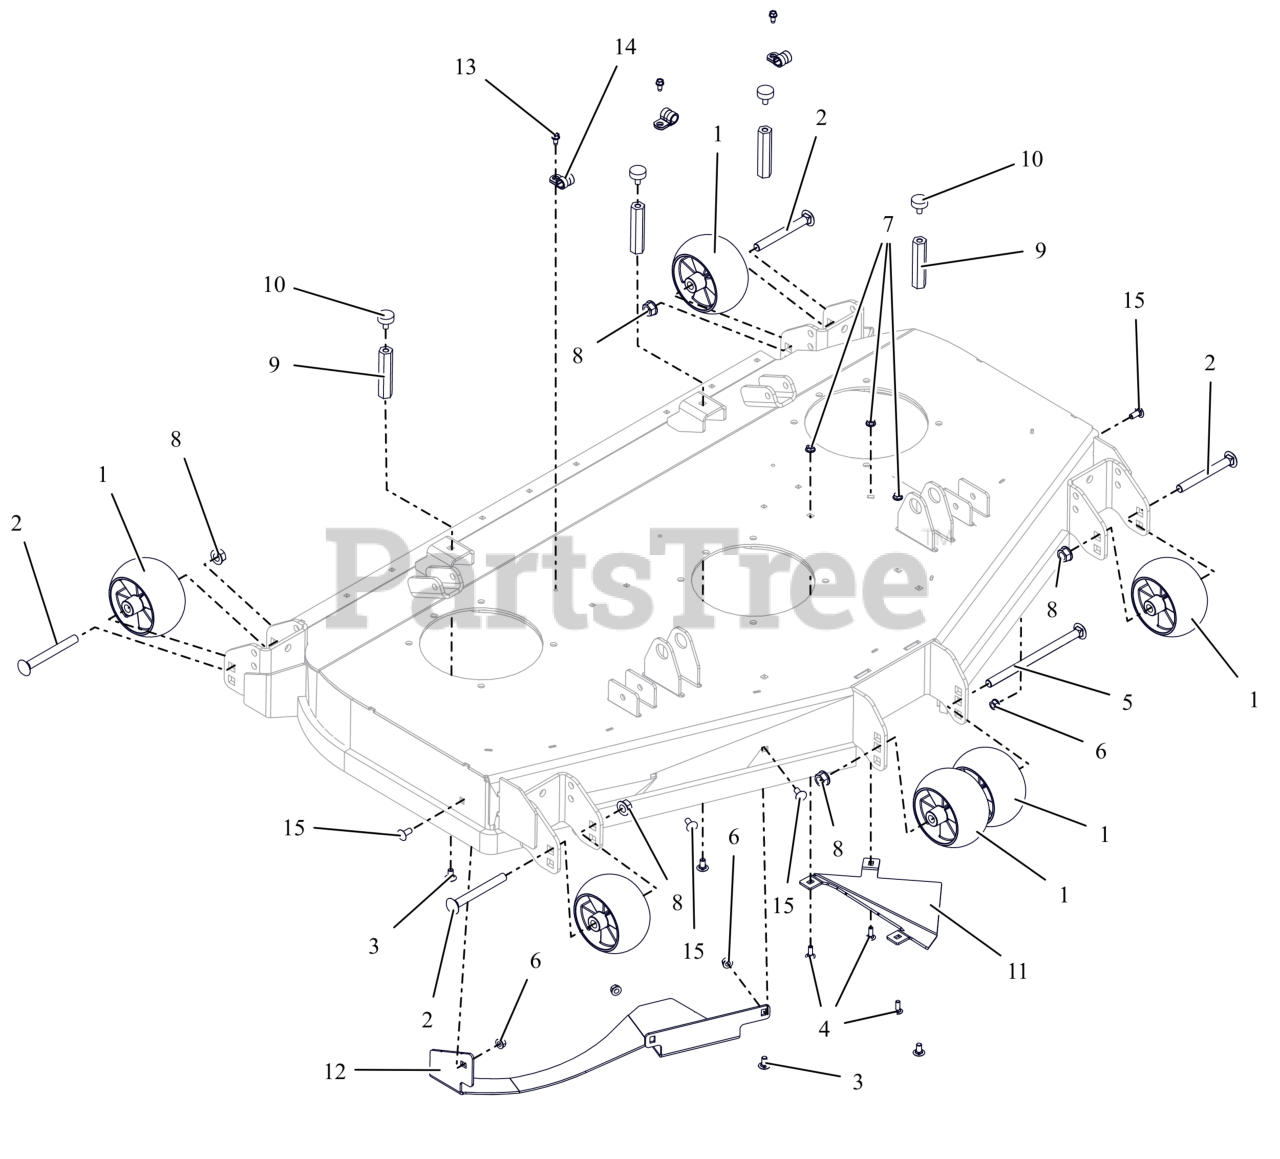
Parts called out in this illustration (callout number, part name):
1	WHEEL, ANTI SCALP - 5X3 CTR W/RIBS
2	BLT,RHNS .50-13X4.50 G5 ZCC NS
3	BTL,RHSSN .313-18 X 0.625 G5 ZCC
4	BLT, RHSN .25-20X.750 G5 ZCC
5	BLT,RHSN .50-13X8.00 G5 ZCC NS
6	NUT,LK-CTR-FLG .31-18 GF ZCC
7	NUT-LK-CTR-FLG .25-20 ZC120
8	NUT-LK-CTR-FLG .500-13 GG ZCC
9	NUT, COUPLING .312-18 X 3.375
10	BUMPER, RUBBER
11	BAFFLE- 52" TRIANGLULAR INSERT
12	DEFLECTOR- 52" BOLT-IN BAFFLE
13	SCR-TAP .25-20X.50 HWH ZCC
14	CLAMP, CUSHIONED STEEL
15	BLT, RHSSN.31-18X.750 G5 ZCC
